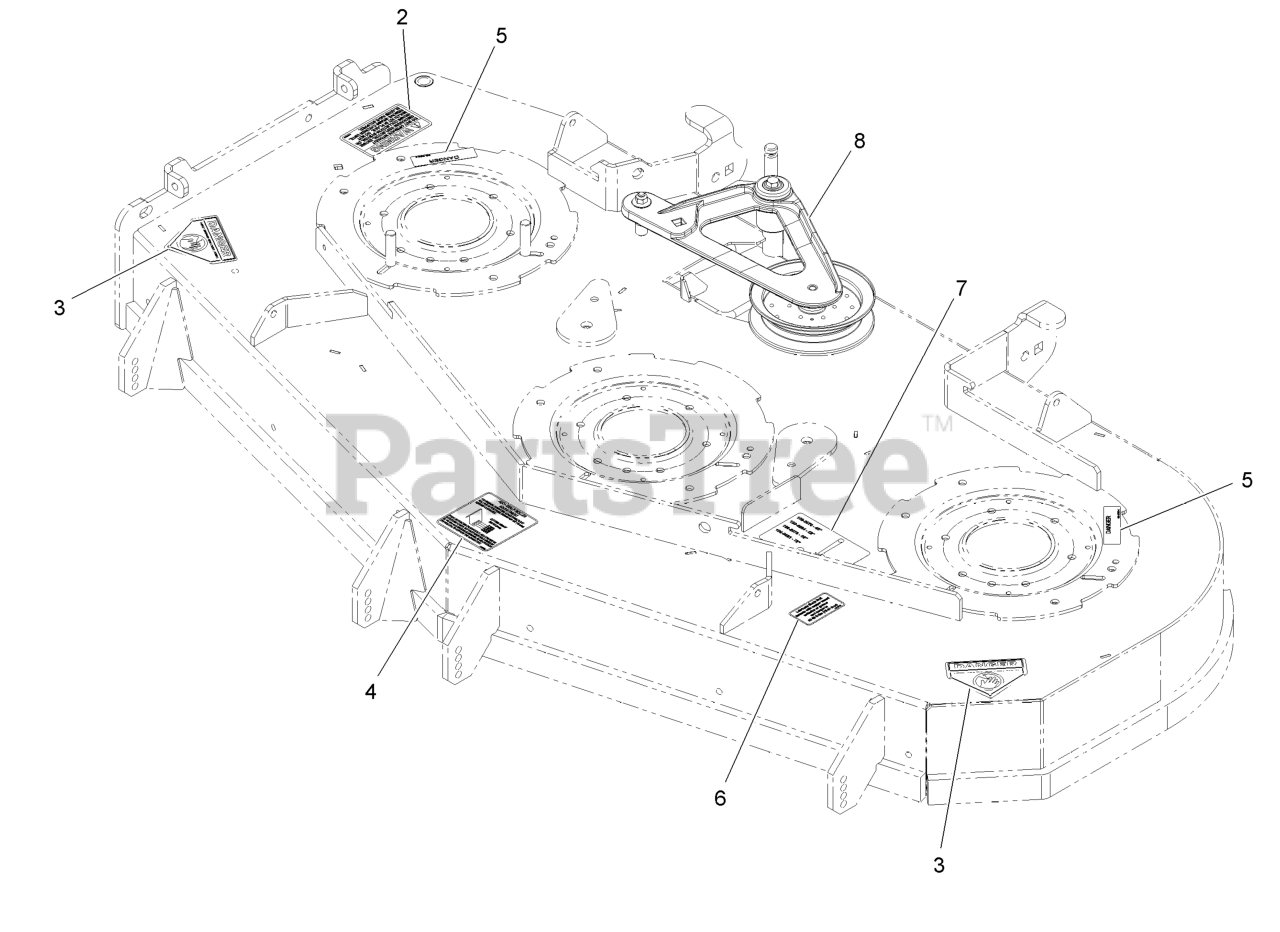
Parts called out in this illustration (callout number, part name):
2	DECAL-WARNING, DISCHARGE
3	DECAL-DANGER
4	DECAL,ANTISCALP
5	DECAL-COVER, MISSING
6	DECAL,BOLT TORQUE
7	DECAL,BELT ROUTING
8	DECK IDLER ASM
